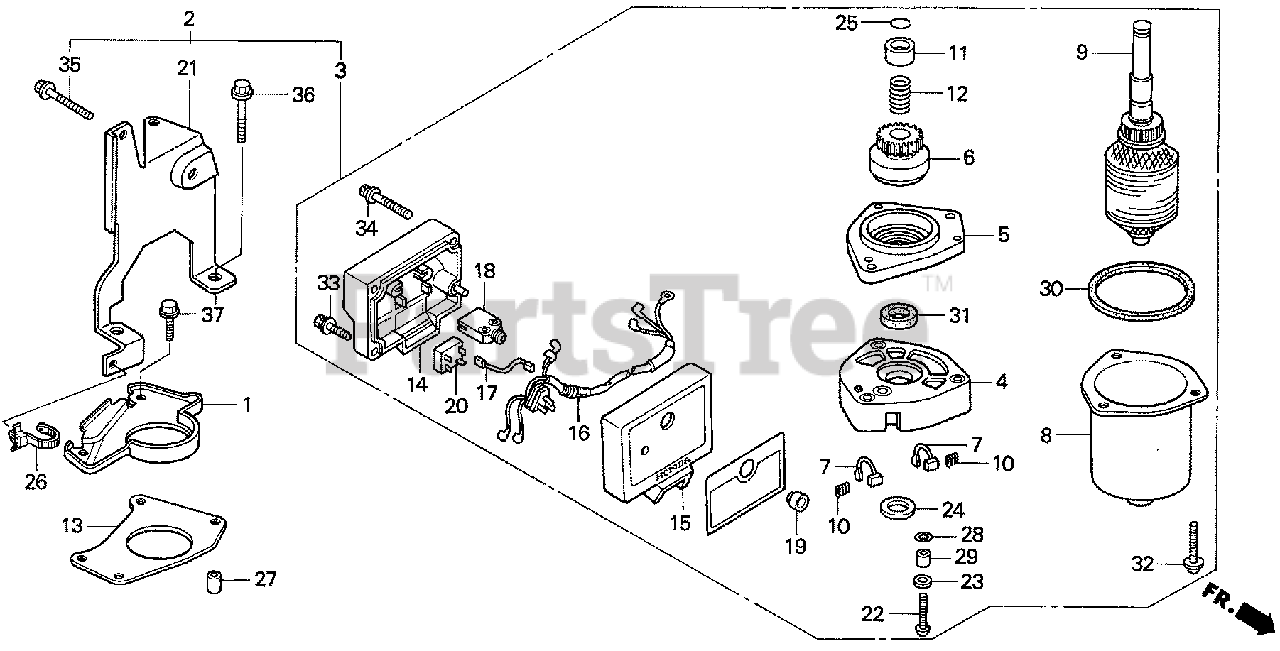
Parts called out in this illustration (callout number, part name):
1	PLATE, SIDE
2	MOTOR ASSY., STARTER (A.C.)
3	MOTOR ASSY., STARTER
4	HOUSING, CENTER
5	HOUSING, PINION
6	CLUTCH
7	BRUSH
8	YOKE
9	ARMATURE
10	SPRING, BRUSH RETURN
11	STOPPER, PINION
12	SPRING, COIL
13	BRACKET, STARTER MOTOR
14	COVER
15	CASE
16	WIRE
17	SUB-WIRE
18	SWITCH, STARTER (Honda Code 2299584). (A.C. 380V-16A)
18	SWITCH, STARTER (Honda Code 2773141). (A.C. 250V-16A)
19	CAP
20	DIODE
21	BRACKET, SWITCH BOX
22	SCREW, TRUSS (4X30)
23	WASHER, STAR (4MM)
24	WASHER B
25	RING, RETAINING
26	STRAP, CABLE (105MM) *NH1* (Honda Code 1685536). (BLACK)
27	PIN A, DOWEL (10X14)
28	O-RING
29	COLLAR
30	GASKET
31	OIL SEAL
32	SCREW-WASHER (5X40)
33	SCREW-WASHER (4X20)
34	SCREW-WASHER (4X30)
35	BOLT, FLANGE (6X40)
36	BOLT, FLANGE (8X25)
37	BOLT, FLANGE (8X28)
